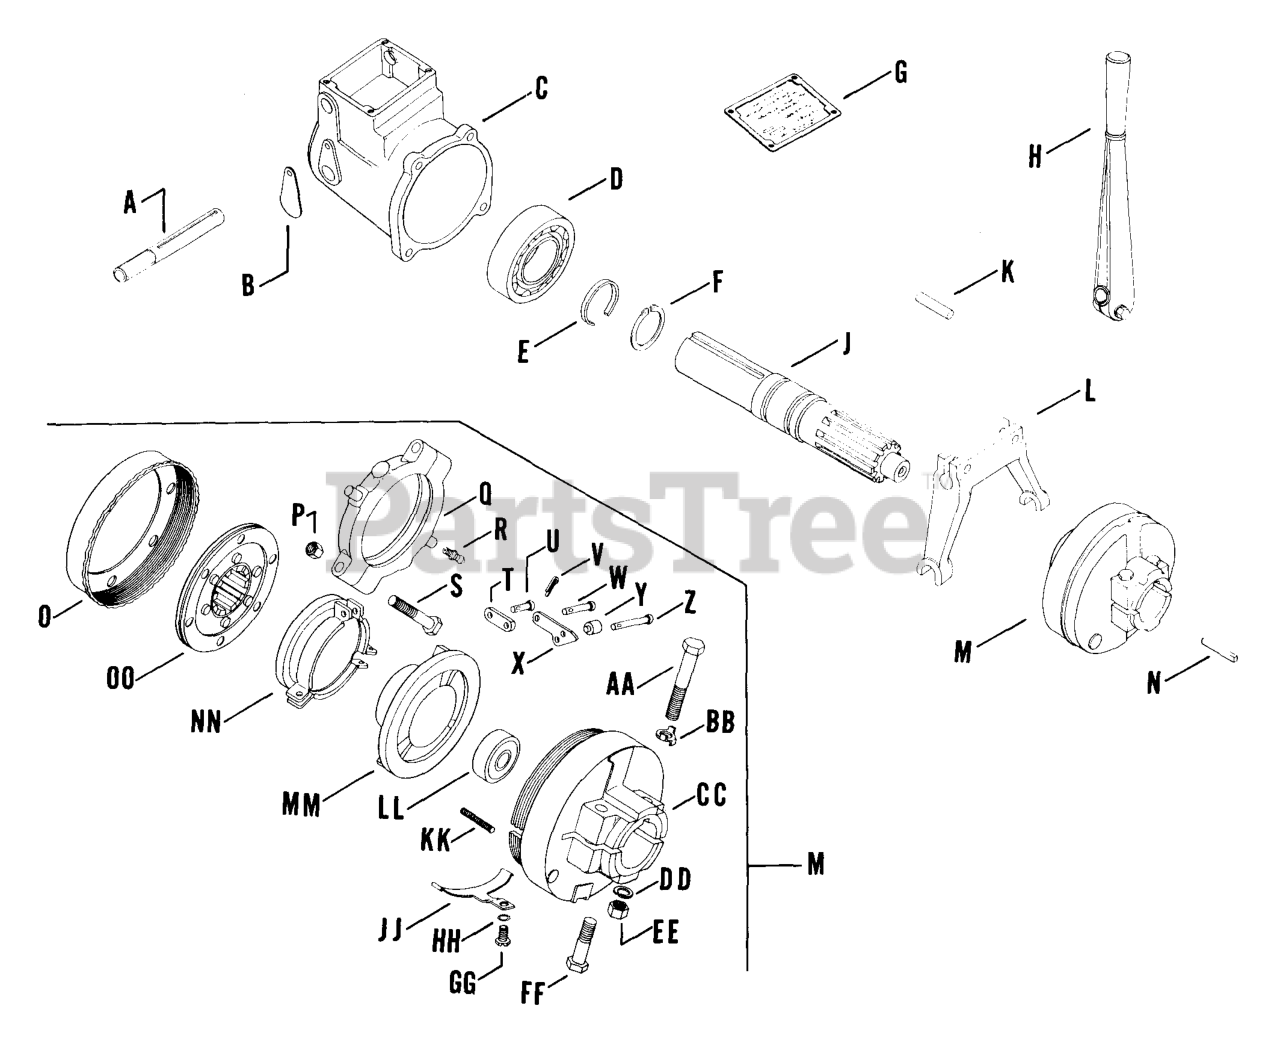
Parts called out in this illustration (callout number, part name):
A	SHAFT - DISCONTINUED
D	BEARING - DISCONTINUED
E	SNAP RING - DISCONTINUED
G	Nameplate, housing
H	LEVER - DISCONTINUED
L	YOKE - USE 24 471 01
Q	BEARING - DISCONTINUED
S	Screw, hex. hd. 5/16-24 x 1-3/4
T	LINK - DISCONTINUED
W	PIN - DISCONTINUED
Y	ROLLER - DISCONTINUED
Z	PIN - DISCONTINUED
AA	SCREW - DISCONTINUED
BB	LOCK - DISCONTINUED
CC	Housing, clutch
DD	WASHER, SPRING LOCK 5/16"
EE	Nut, elastic stop 3/8-24
GG	SCREW - DISCONTINUED
HH	WASHER, INT TOOTH LOCK 1/4"
KK	SPRING - DISCONTINUED
LL	Bearing, pilot
